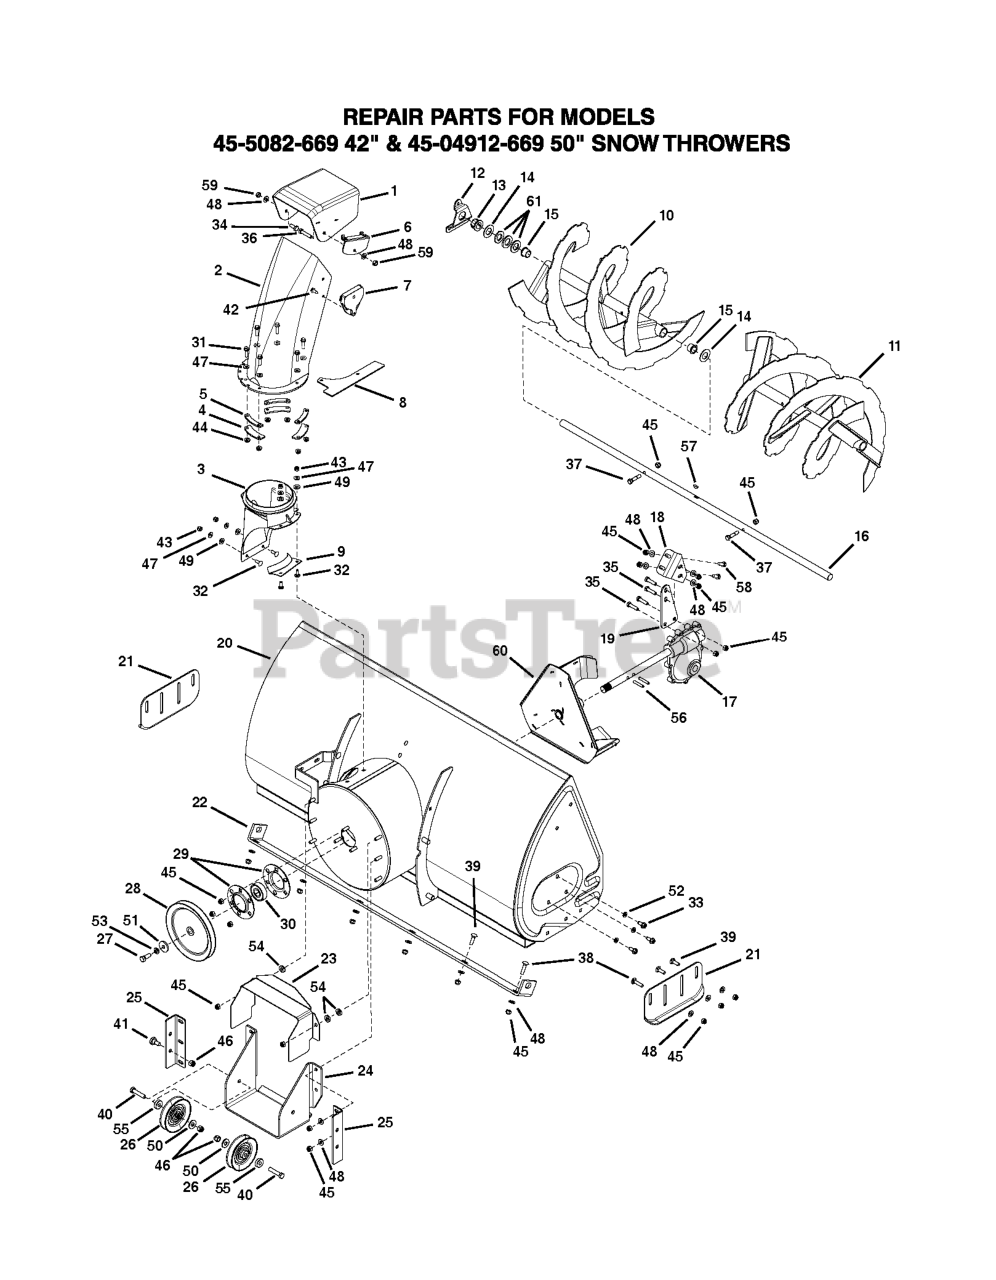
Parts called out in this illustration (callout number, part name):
13	BEARING
16	SHAFT
17	GEAR BOX 71464
21	SKID SHOE
22	PLATE
23	COVER 24816
26	PULLEY 47044
27	BOLT
28	PULLEY 47026
31	BOLT
32	BOLT
33	BOLT
35	BOLT
36	BOLT
38	BOLT
41	BOLT 48106
44	NUT
45	NUT 47810
46	NUT
47	WASHER
48	WASHER
49	WASHER
52	LOCK WASHER
53	LOCK WASHER
57	KEY
59	NUT
